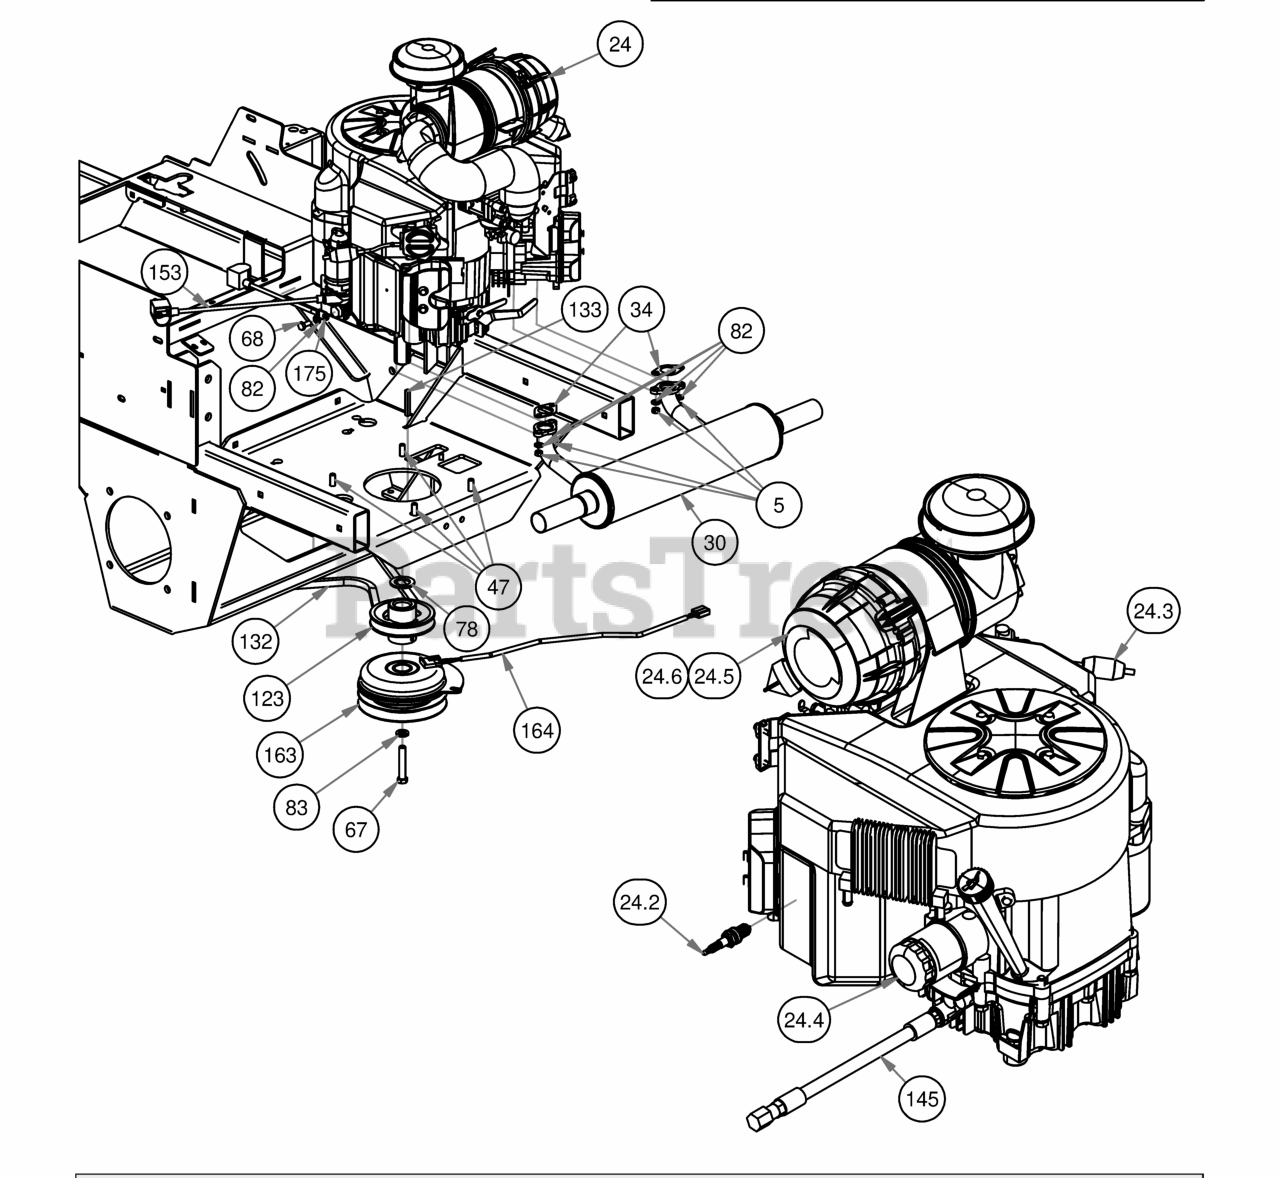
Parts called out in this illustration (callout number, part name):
5	M8-1.25 Zinc Nut
24	Kawasaki FX850 Engine
24.2	Spark Plug - Kawasaki
24.3	Universal Inline Fuel Filter
24.4	Oil Filter
24.5	Canister Air Filter- Outer
24.6	Canister Air Filter- Inner
30	2019 Rebel/Rogue Kawasaki 850 Muffler
34	Exhaust Gasket
47	3/8 x 1 1/8 bolt
67	7/16" x 2 1/2" Hex Bolt
68	M8x1.20x20MM Hex head bolt
78	1 1/8" Flat Spacer
82	5/16" Lock Washer
83	7/16" Lock Washer
123	4 3/4 Motor Pulley
132	2019 Rebel Pump Belt
133	1/4 x 2 Square key Stock
145	Kawasaki Oil Drain
153	14" Red Battery Cable-Base Outlaw
163	Clutch Assembly
164	Clutch Pigtail
165	2019 Rigid Frame
175	Starter Cable
